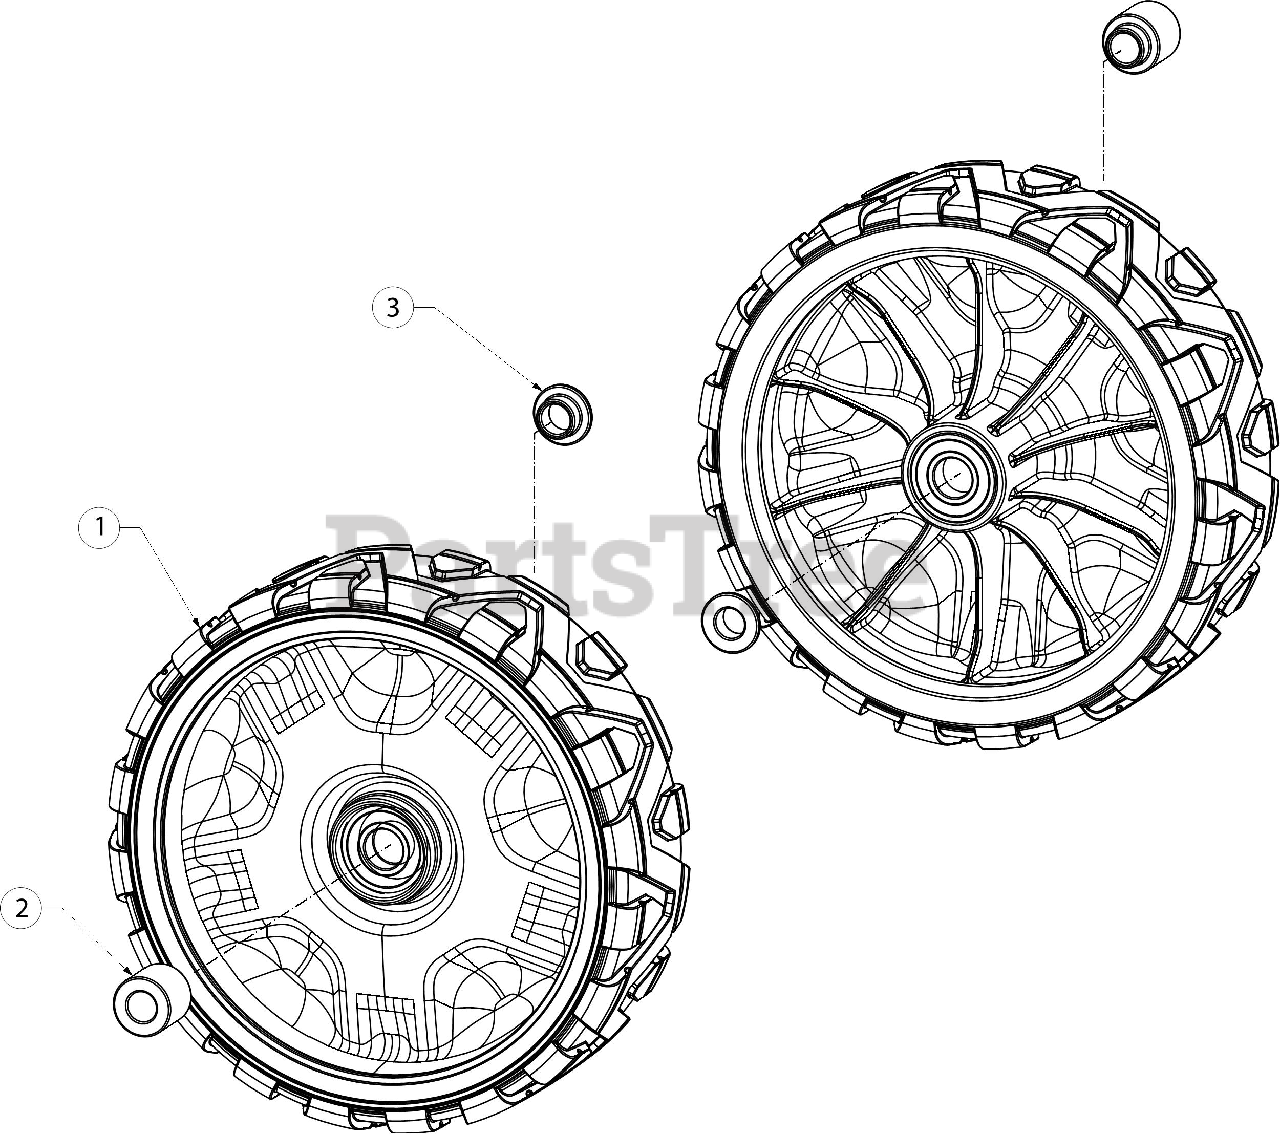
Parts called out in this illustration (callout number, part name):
1	WHEEL ASSEMBLY (7 X 2)
1	BALL BEARING
2	CASTER HUB
3	CASTER HUB
